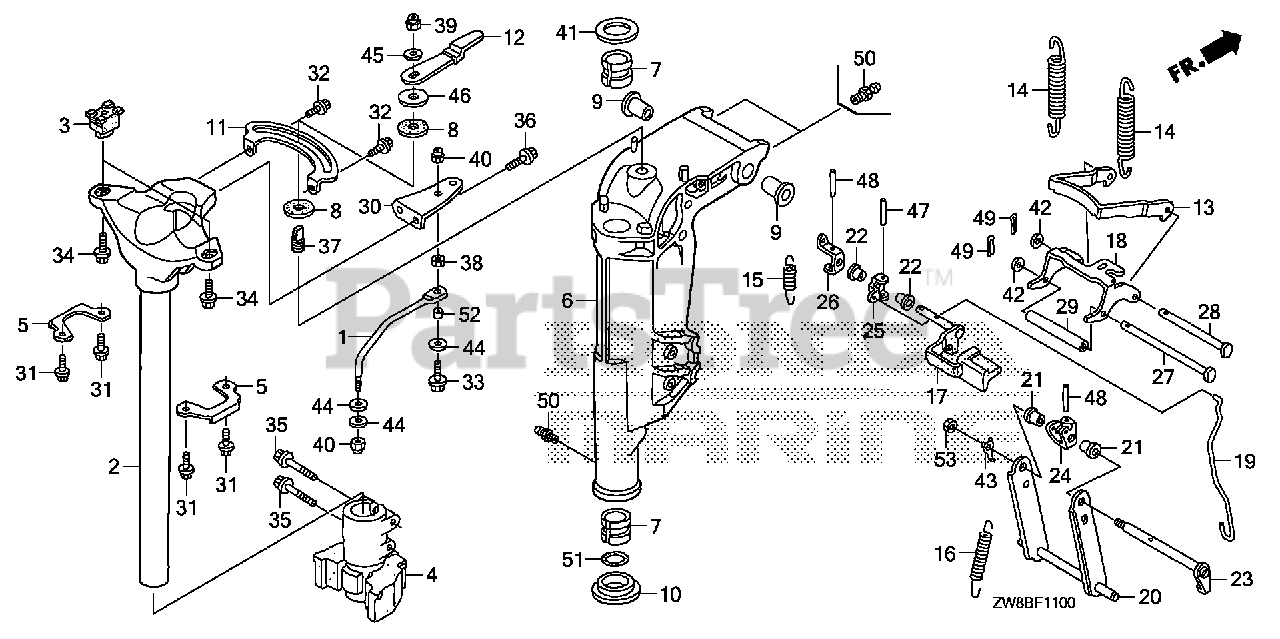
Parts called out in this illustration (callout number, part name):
2	FRAME, MOUNTING (S)
3	RUBBER, MOUNTING (UPPER)
4	RUBBER, MOUNTING (LOWER)
5	COVER, MOUNTING RUBBER (UPPER)
6	CASE, SWIVEL *NH282MU* (S) (OYSTER SILVER METALLIC-U)
7	LINER, SWIVEL CASE
8	BLOCK, FRICTION
9	BUSH, SWIVEL CASE
10	COLLAR, SWIVEL CASE
11	PLATE, FRICTION
12	LEVER, FRICTION
13	HOOK, REVERSE LOCK
14	SPRING, REVERSE LOCK
15	SPRING, TILT LEVER
16	SPRING, TILT LINK
17	LEVER, TILT
18	ARM, REVERSE LOCK
19	ROD, RELEASE SWIVEL CASE
21	BUSH, TILT LEVER
22	BUSH, TILT LEVER
23	SHAFT, TILT
24	BRACKET, TILT SHAFT
25	BRACKET, RELEASE ROD
26	BRACKET, TILT LEVER
27	SHAFT, REVERSE LOCK (A)
28	SHAFT, REVERSE LOCK (B)
29	COLLAR, REVERSE LOCK
31	BOLT, FLANGE (6X12)
32	BOLT, FLANGE (6X12)
34	BOLT, FLANGE (10X25)
35	BOLT, FLANGE (8X45)
37	BOLT, STUD (8X26)
39	NUT, SELF-LOCK (8MM)
41	WASHER, THRUST
42	WASHER, PLAIN (6MM)
43	WASHER, LOCK
45	WASHER (8MM)
46	WASHER, NYLON (8MM)
47	PIN, SPRING (3.0X22)
48	PIN, SPRING (3.0X25)
49	PIN, SPLIT (2.0)
50	NIPPLE, GREASE
51	O-RING (34X2.4)
53	NUT, HEX. (6MM)
